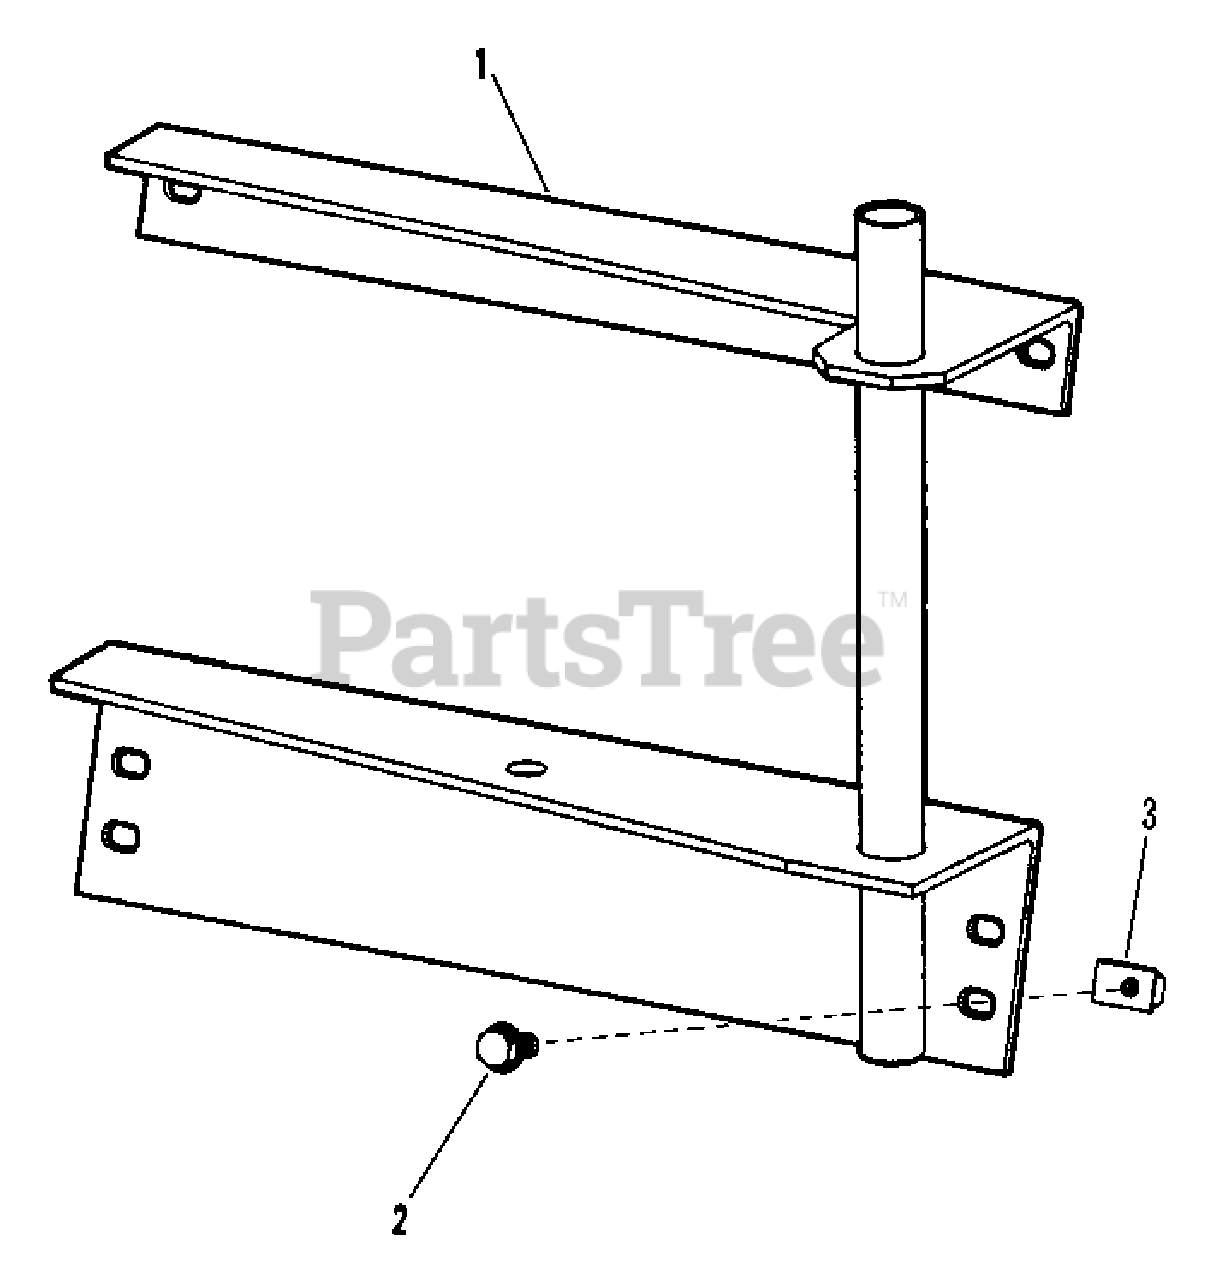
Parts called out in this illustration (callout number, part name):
1	WELDMENT, Adapter
2	BOLT, 5/16-18 x 3/4" Hex Flange Lock, Grade 5
3	NUT, 5/16" Push-on
